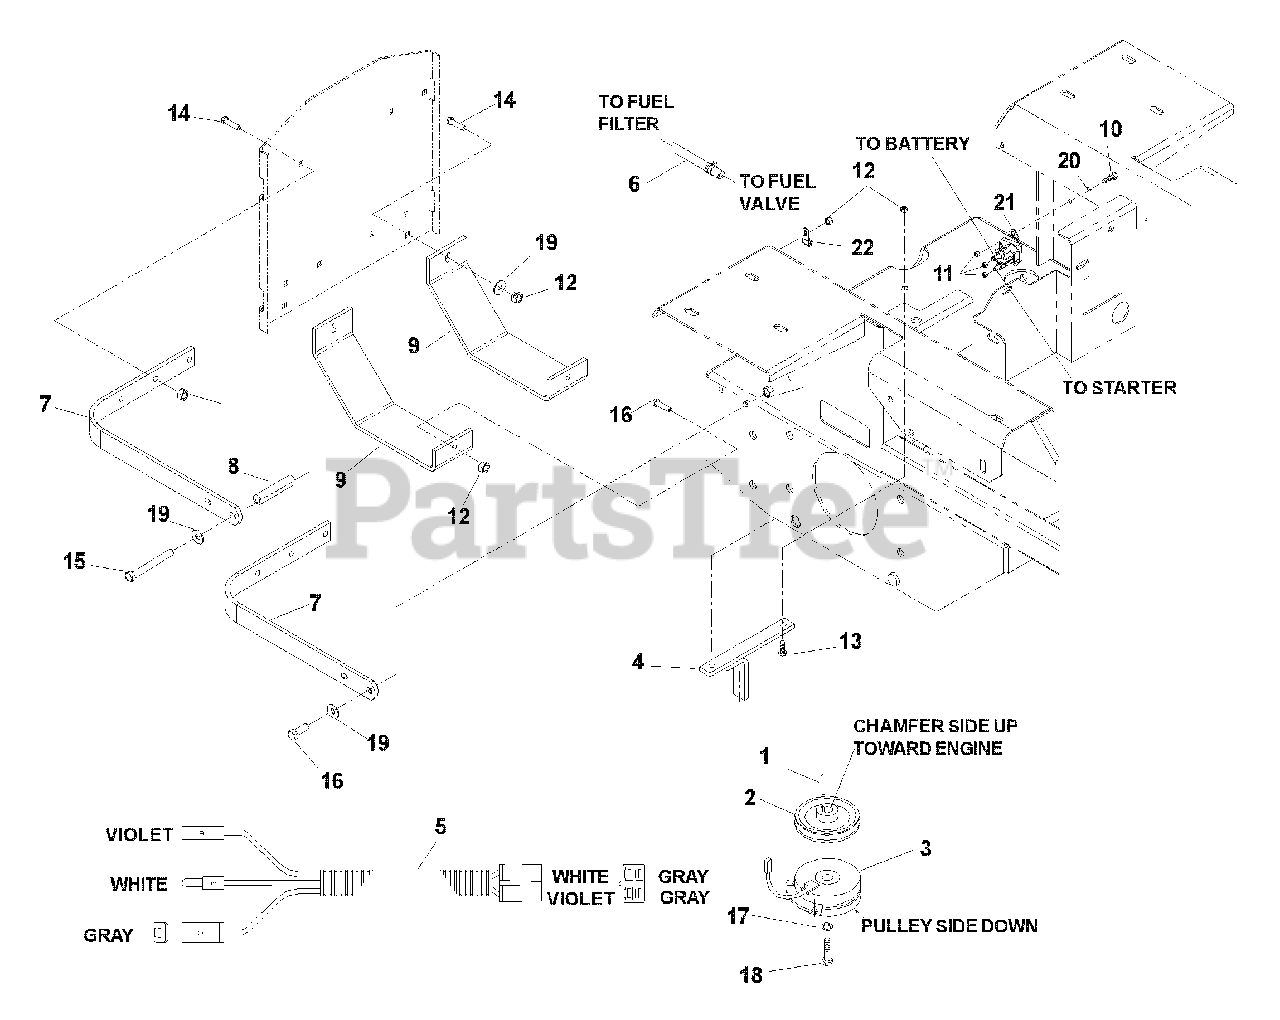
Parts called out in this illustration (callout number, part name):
1	KEY, 1/4 SQ X 1 1/4
4	CLUTCH TIE DOWN
6	FUEL HOSE, 29.5"
9	SKID PLATE
10	HCS, 1/4C X 5/8
11	NUT, 1/4C, NYLOC
12	NUT, 5/16C, NYLOC
13	HCS, 5/16C X 1 3/4
14	RHSSNB 5/16C X 1
15	HCS, 5/16C X 4
16	HCS, 5/16C X 1
17	LOCKWASHER, 7/16
18	HCS, 7/16F X 2 1/2
19	WASHER, 5/16, FLAT
20	LOCKWASHER, 1/4 IT
22	DOUBLE TUBE CLAMP
